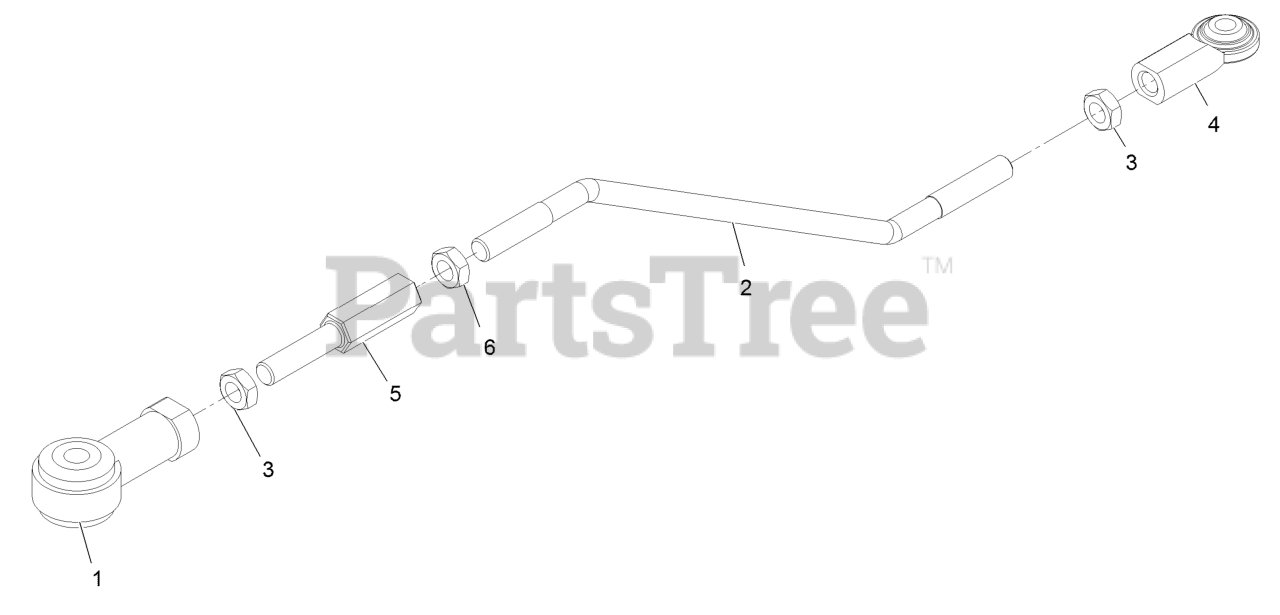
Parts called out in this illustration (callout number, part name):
1	End-Rod, Isolated
2	Rod-Linkage, Rear
3	Nut-Jam 3/8-24
4	Balljoint
5	Rod-Adjustment
6	Nut-Jam 3/8-24 LH
